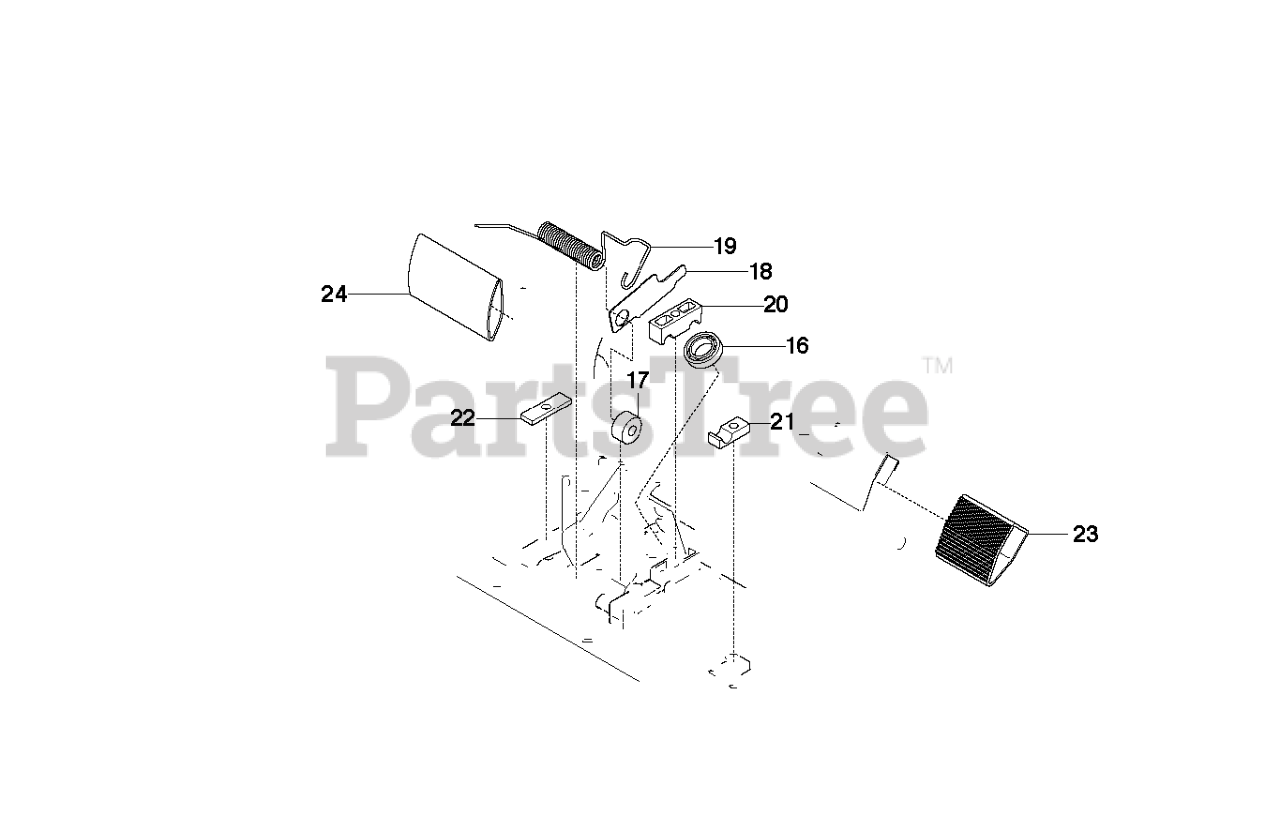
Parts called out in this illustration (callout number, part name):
16	BALL BEARING 6002-2RS1
17	ROLLER
18	PLATE
19	SPRING
20	PEDAL SHAFT CLAMP
21	SUPPORT
22	PLATE
23	PEDAL RUBBER
24	PEDAL RUBBER, SF
